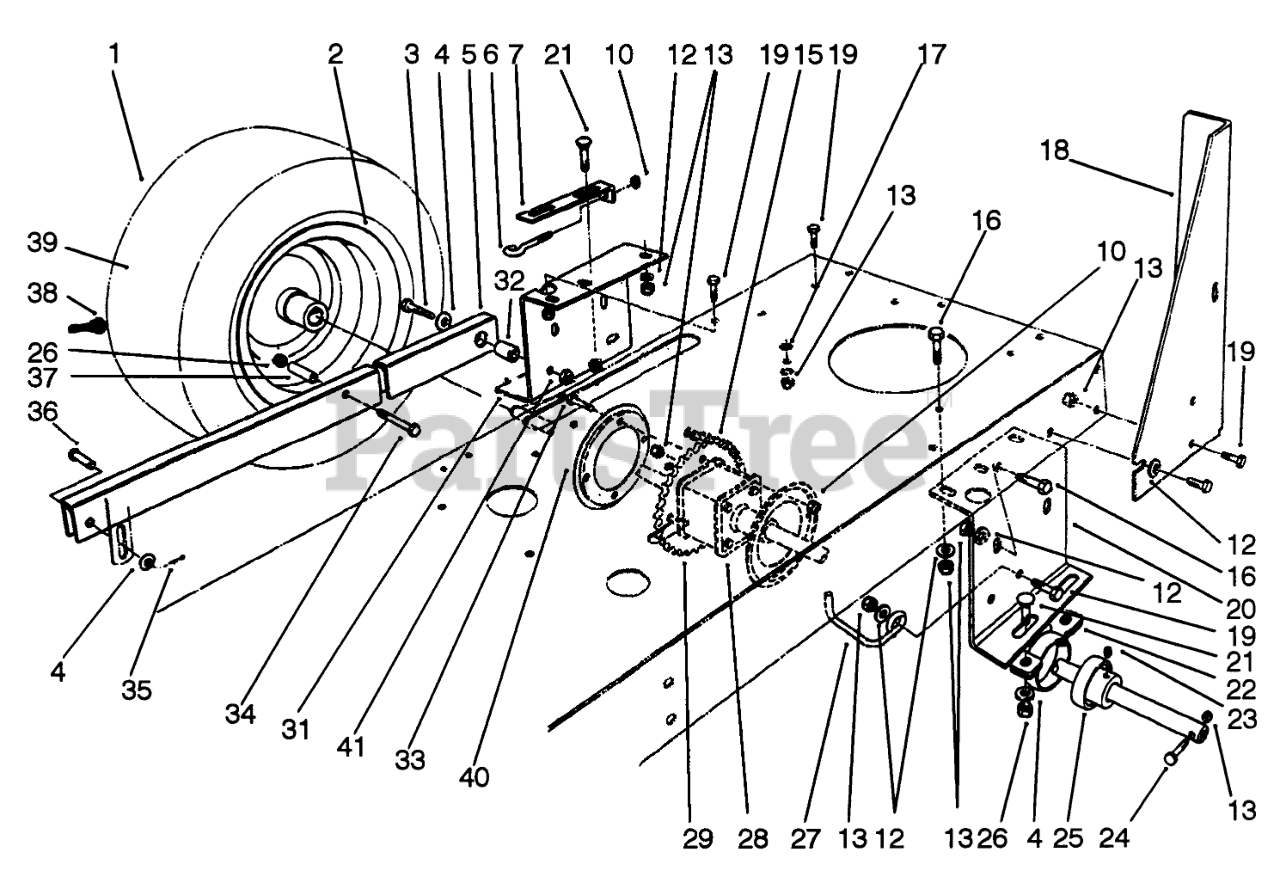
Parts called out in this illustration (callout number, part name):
3	SCREW-HH
4	WASHER-FLAT
5	Arm-Suspension R.H.
6	SCREW-ADJUSTING
7	PLATE-ADJUSTING
10	NUT-HEX
12	WASHER-PLAIN
13	NUT-LOCK, NI
15	ROLLER CHAIN
16	SCREW-HH
17	WASHER-LOCK, INTERNAL
18	LH STANDBAR B
19	SCREW-HH
20	LH REAR AXLE SUPT R
21	BOLT-CARR
22	RTNR-PILLOW BLK
23	SCREW-SET, HSH
24	AXLE MTG BOLT
25	Bearing-Ball (Incl. Ref. #23)
26	NUT-LOCK, NI
27	BELT GUIDE
28	DIFFERENTIAL
29	SPROCKET
31	RH AXLE SUPPORT R
32	PIN-SUPT ARM
33	SCREW-HH
34	SCREW-HH
35	PIN-COTTER
36	PIN-CLEVIS
37	SPACER-SPLIT TUBE
38	STEM-VALVE
39	TUBE-INNER
40	Guide-Chain
41	NUT-LOCK, NI
